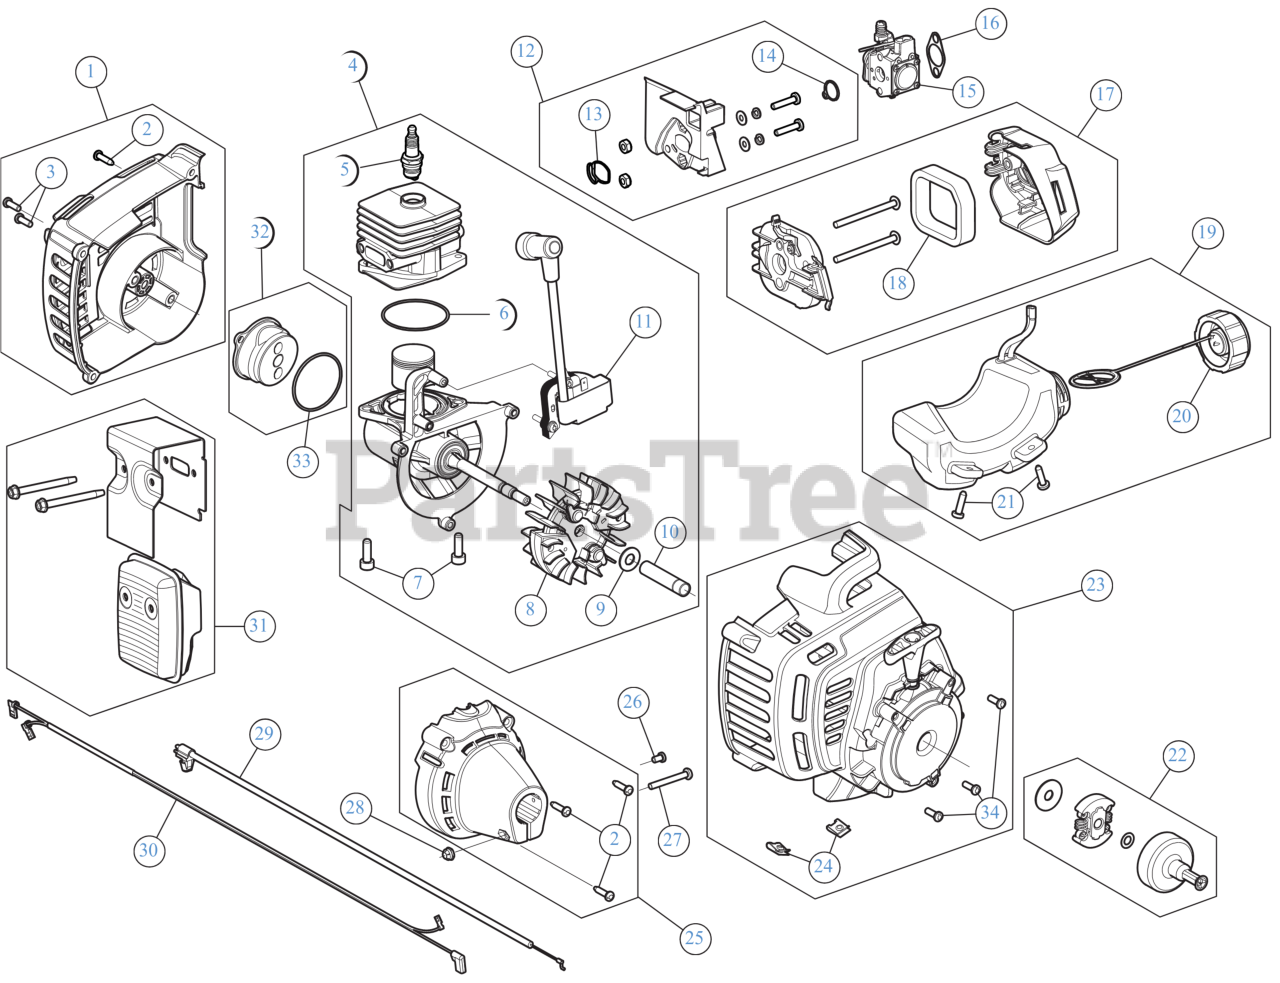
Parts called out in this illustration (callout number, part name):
1	REAR ENGINE COVER
2	SCREW, #8-16X.750 PH
3	SCREW #
4	SHORT BLOCK
5	SPARK PLUG
6	O-RING
7	SCREW, 1/4-20 x .75
8	FLYWHEEL ASSEMBLY
9	BELL WASHER
10	SPACER
11	MODULE 27CC DIG
12	INTAKE ASSEMBLY
13	O-RING
14	O-RING
15	CARBURETOR
16	GASKET CARB
17	AIR CLEANER ASSEMBLY
18	AIR FLITER
19	FUEL TANK ASSEMBLY
20	FUEL CAP ASSEMBLY
21	SCREW:10-6 x .75
22	SMALL CLUTCH ASSEMBLY W/SMALL DRUM
23	STARTER HOUSING ASSEMBLY
24	NUT, TINNERMAN U-T
25	CLUTCH COVER
26	SCREW, 8-32 x .312 P
27	SCREW
28	HEX NUT
29	THROTTLE CABLE
30	LEAD WIRES
31	MUFFLER ASSEMBLY
32	ELECTRIC START COVER
33	O-RING
34	SCREW:10-32X.562:#8P
